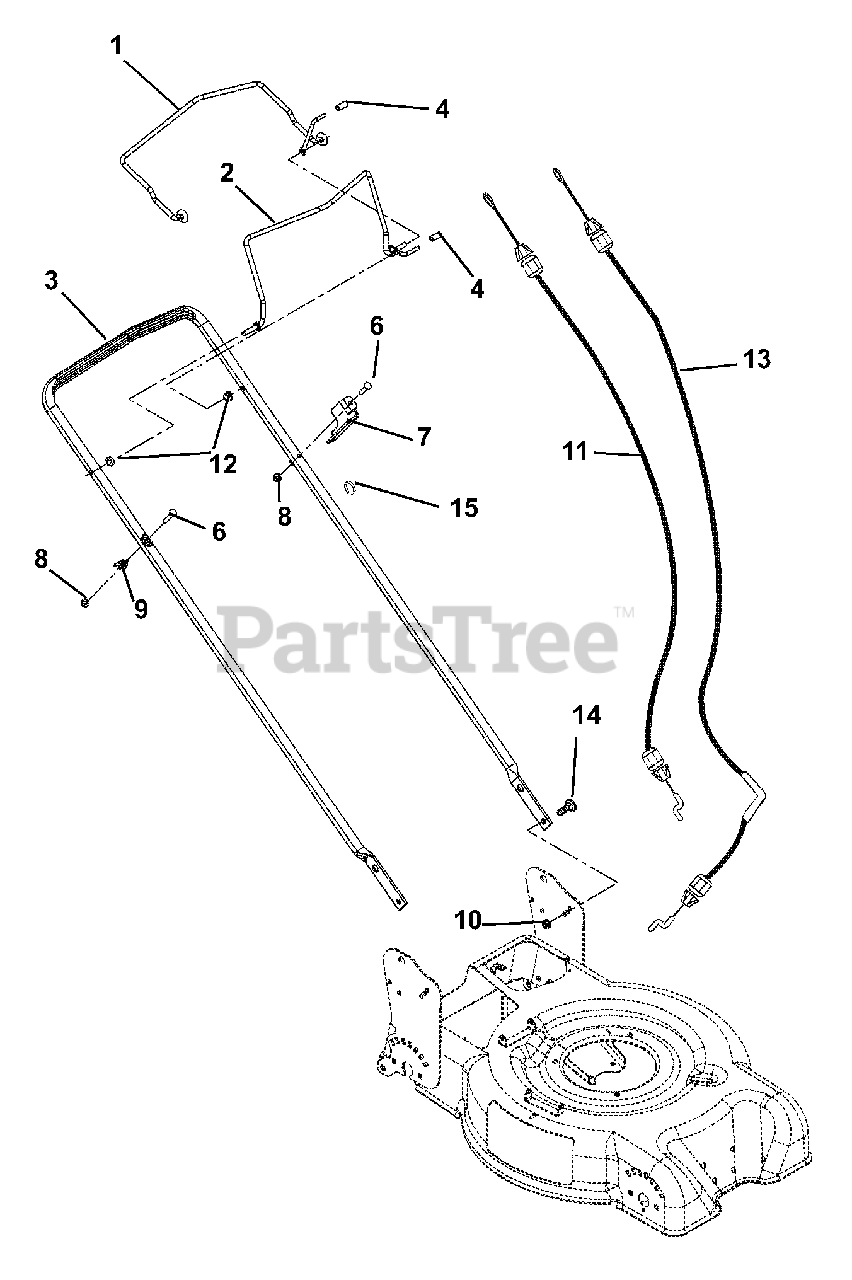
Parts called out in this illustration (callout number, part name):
1	Bail, Drive
2	Bail, Operator Presence
3	Handlebar
4	Cap, Vinyl .25 I.D.
5	Cap, Vinyl .25 I.D.
6	Bolt, Round Head Square Neck .25-20 x 1.25
7	Anchor, Cable
8	Nut-Locking-Top-Flange .25-20
9	Guide, Pullcord
10	Nut, Flange Spinlock .312-18
11	Cable, Operator Presence
12	Bushing-Flange .325 x .444 x.440 x.560
13	Cable, Traction
14	Bolt, Round Head Square Short Neck .31-18 x .75 Grade 5
15	Clip, Conduit
